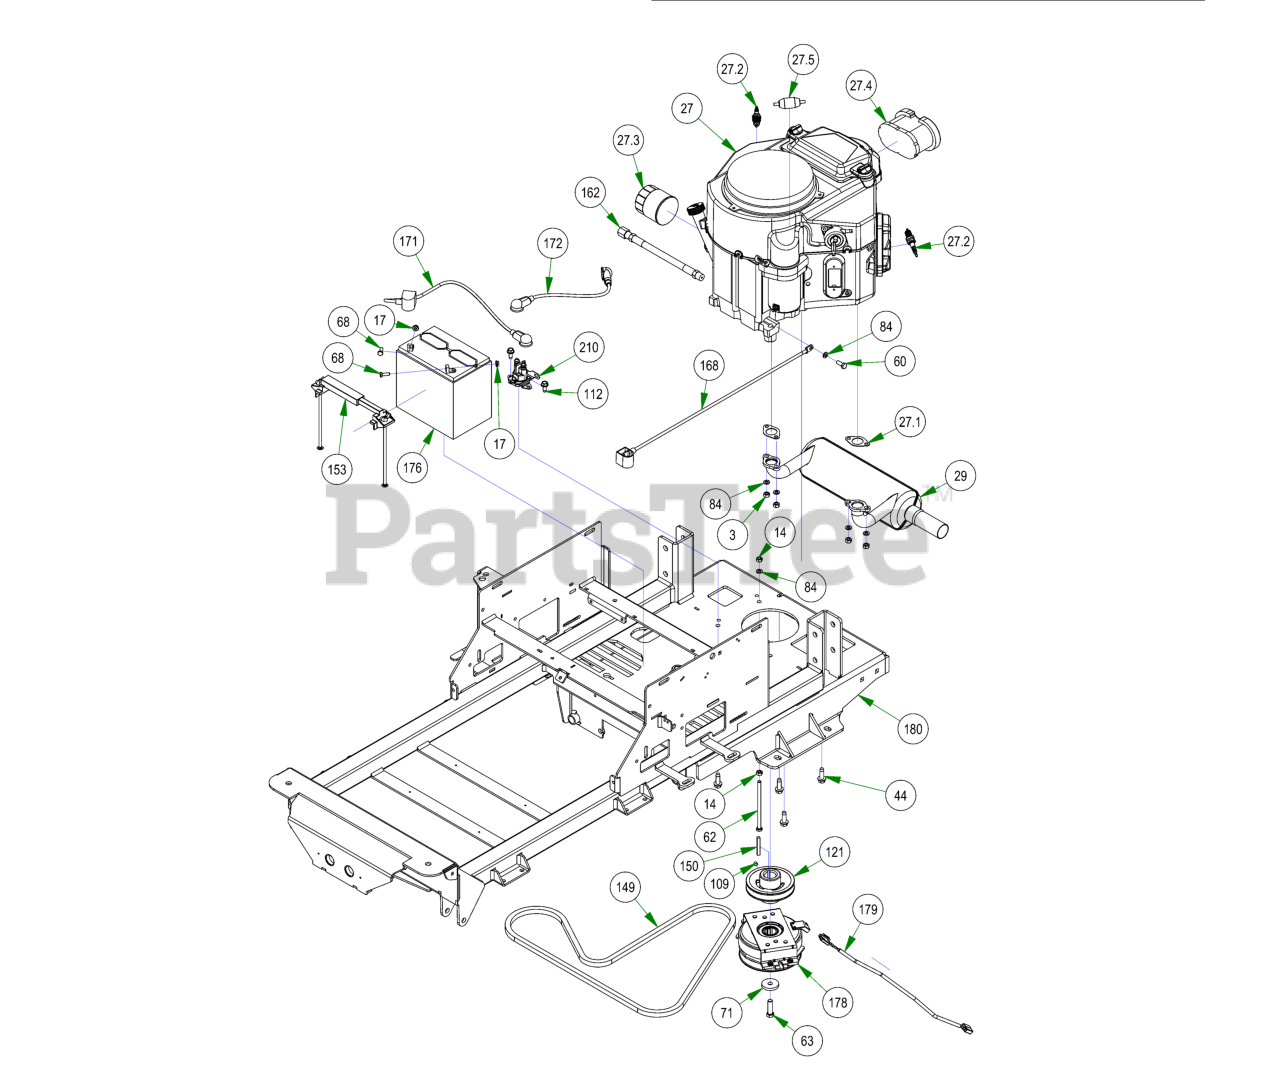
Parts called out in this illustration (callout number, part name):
3	M8-1.25 DIN 934 HEX NUT (CL.8) ZINC
14	5/16-18 HEX NUT ZINC
17	1/4-20 HEX SERRATED FLANGE NUT HARD/ZINC
27	FS730V Engine
27.1	Exhaust Gasket
27.2	Spark Plug - Kawasaki
27.3	22-26 Kaw Oil Filter FR Engine
27.4	Kawasaki Air Filter
27.5	Universal Inline Fuel Filter
29	Kawasaki Muffler 1251
44	3/8-16 X 1-1/8HEX WASHER UNSLOT SERRATED (TRI-LOB) TRS
60	M8-1.25 X 20MM DIN 933 HEX TAP BOLT (CL 8.8) ZINC
62	5/16-18 X 5-1/2 HEX CAP SCREW (GR.5) ZINC
63	7/16-20 X 1-1/2 HEX CAP SCREW (GR.8) w/ Patch
68	1/4-20 X 3/4 HEX CAP SCREW (GR.5) ZINC
71	CLUTCH WASHER
84	5/16 SPLIT LOCKWASHER ZINC
109	5/16-24 X 1/4 SOCKET SET SCREW (CUP PT) PLAIN
112	5/16-18 X 3/4HEX WASHER SLOT (F) TCS ZINC
121	4 3/4 Motor Pulley
149	75.8" Pump Belt
150	1/4 X 2 SQ MACHINERY KEY 1018 STL PLAIN
153	Hold Down Assembly
162	Oil drain Hose
168	24 inch Black Cable – MZ/ZT
171	24" Red Battery Cable
172	12" Red Battery Cable
176	SP-35 Battery
179	Clutch Pigtail
180	2022 Maverick Frame - Painted
